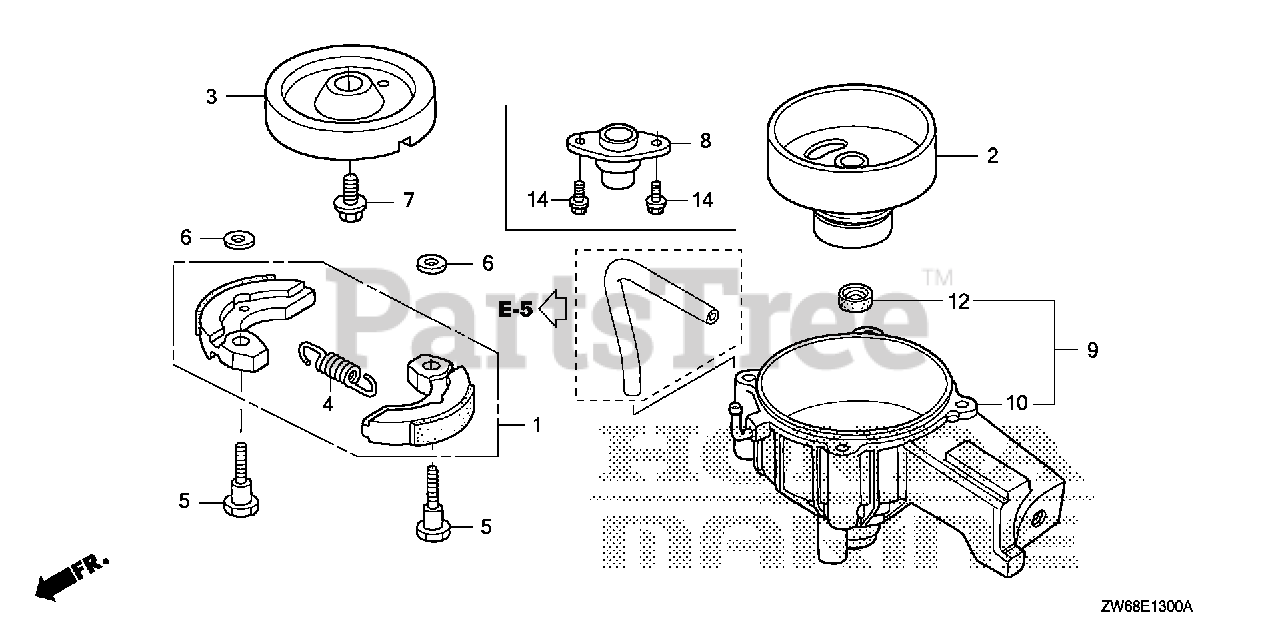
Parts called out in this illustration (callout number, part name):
1	CLUTCH ASSY.
2	CLUTCH OUTER ASSY.
3	STAY, CLUTCH
4	SPRING, CLUTCH SHOE
5	BOLT, CLUTCH (8MM)
6	WASHER, PLAIN (8MM)
7	BOLT, CLUTCH STAY (8MM)
9	HOUSING ASSY., CLUTCH
10	HOUSING, CLUTCH
11	BEARING, RADIAL BALL (6004) (NOT AVAILABLE)
12	SEAL, WATER (11X21X8)
13	CIRCLIP (INNER) (42MM)
